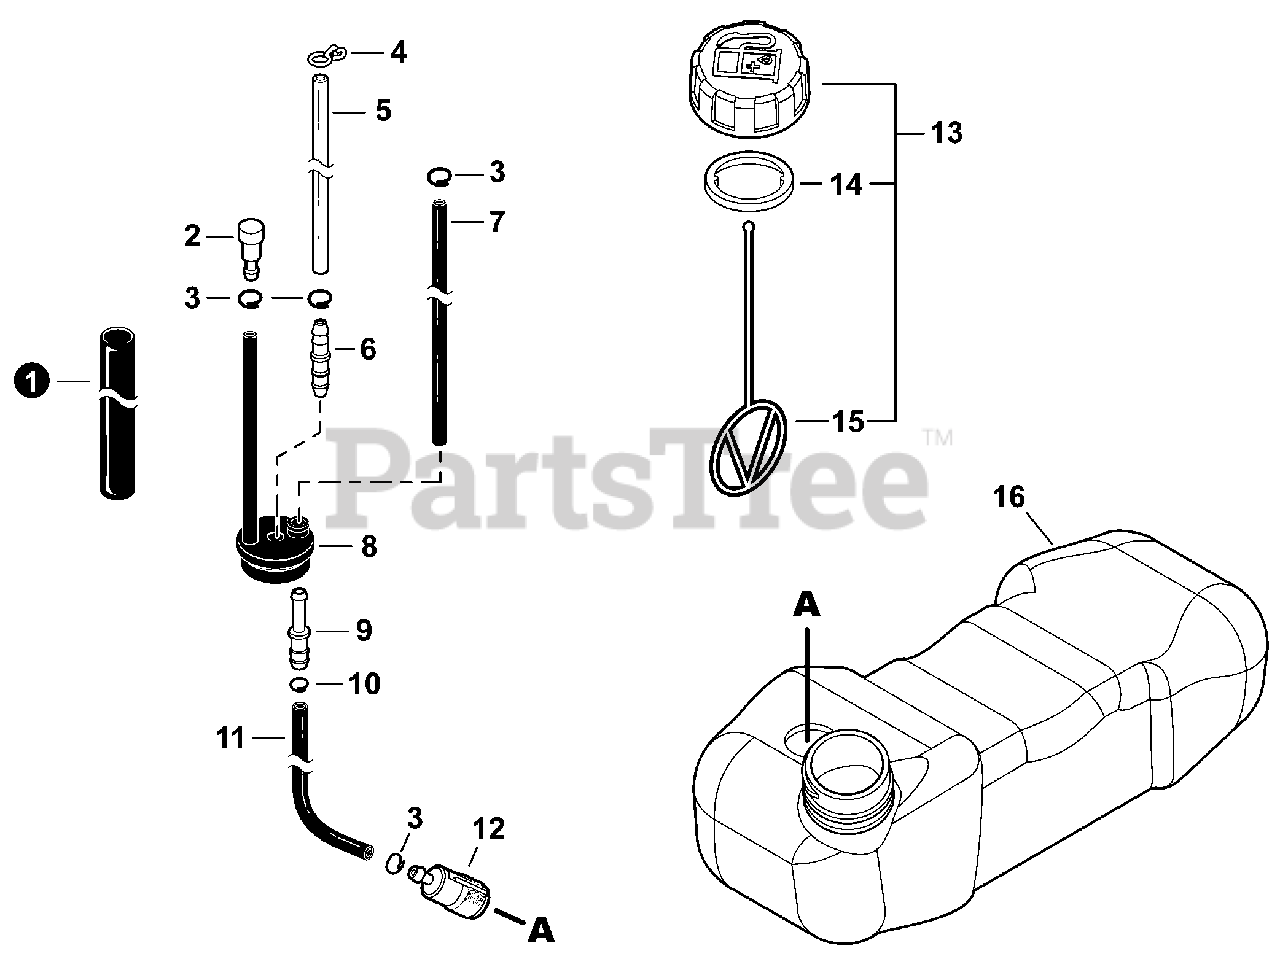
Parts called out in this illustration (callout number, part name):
1	TUBE, PROTECTIVE
2	VENT ASSY
3	CLIP Ø6
4	CLIP, SPRING Ø5.2
5	PIPE, FUEL 3×6×133 CLEAR
6	CONNECTOR, PIPE
7	PIPE, FUEL 3×5×135L BLACK
8	GROMMET, FUEL W/VENT PIPE
9	CONNECTOR, PIPE Ø5ר3.5
10	CLIP Ø6.5 MM
11	PIPE, FUEL 3.3×6×195 BLACK
12	FILTER, FUEL
13	CAP ASSY, FUEL
14	GASKET, FUEL CAP
15	CONNECTOR, CAP L= 100 MM
16	TANK, FUEL
